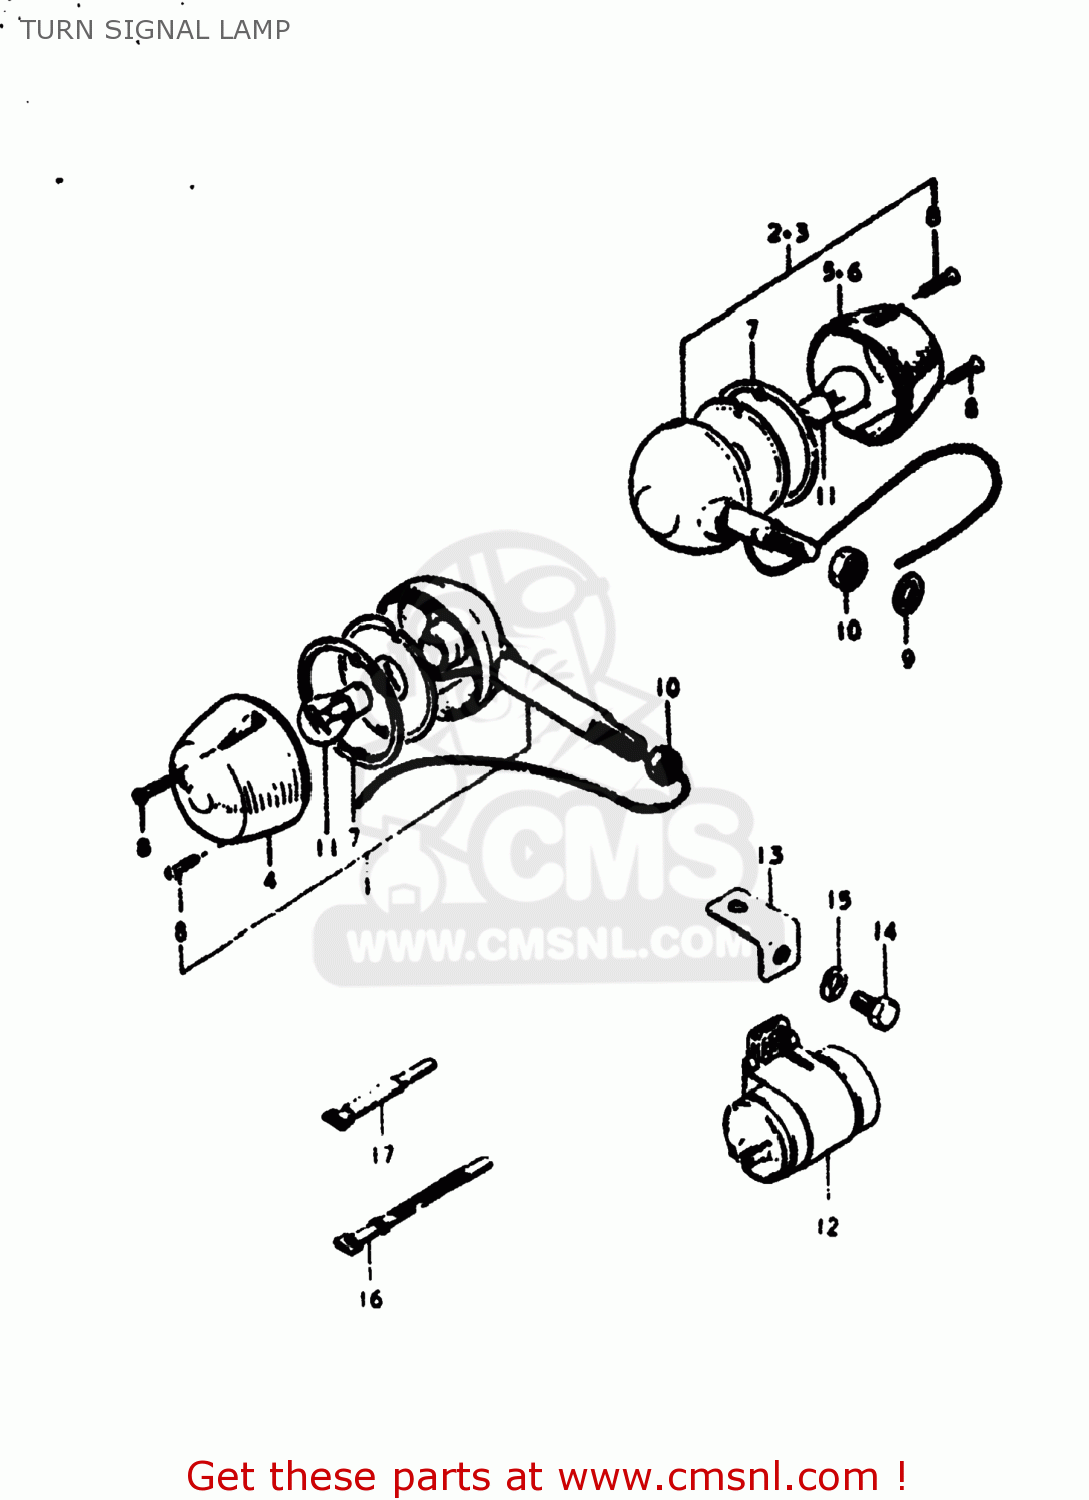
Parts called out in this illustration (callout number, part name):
1	LAMP ASSEMBLY,FRONT TURN SIGNAL
2	LAMP ASSEMBLY,REAR TURN SIGNAL
3	LAMP ASSEMBLY,REAR TURN SIGNAL
4	LENS,TURNSIGNAL
5	LENS,RR TURNSIGNAL LAMP
6	LENS,TURNSIGNAL
7	GASKET,TURNSIGNAL LENS (NAS)
8	SCREW
10	NUT
11	BULB(6V17W,STANLEY,A4513A)
12	RELAY,TURN SIGNAL
13	BRACKET,TURN SIGNAL RELAY
14	BOLT
15	LOCK WASHER
16	CLAMP(L:120)
17	CLAMP
